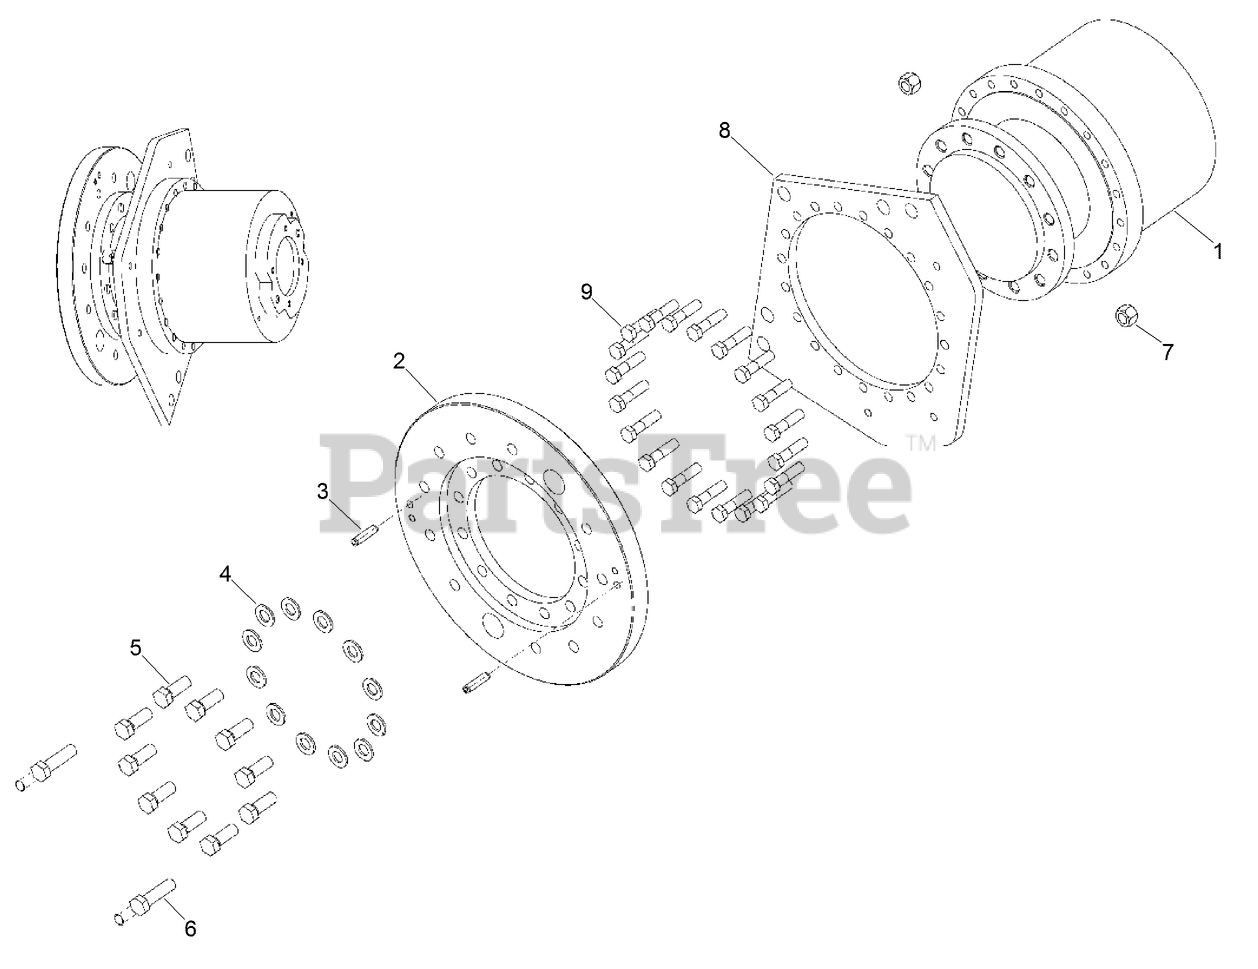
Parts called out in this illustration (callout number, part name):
1	GEARBOX - Model 10 Spindle Output Drive
2	PLATE - Gearbox Mount
3	PIN - Slid Spring, .500 x 2.00 in C-Z
5	BOLT - Hex Hd, .750 UNF x 2.00 GR5 ZND
6	BOLT - Hex Hd, .750 x 2.75 GR8 ZND
7	NUT-hex, self-locking, 3/4 inch NF
8	PLATE - Wheel Mount
9	BOLT - 5/8 x 2-1/2
